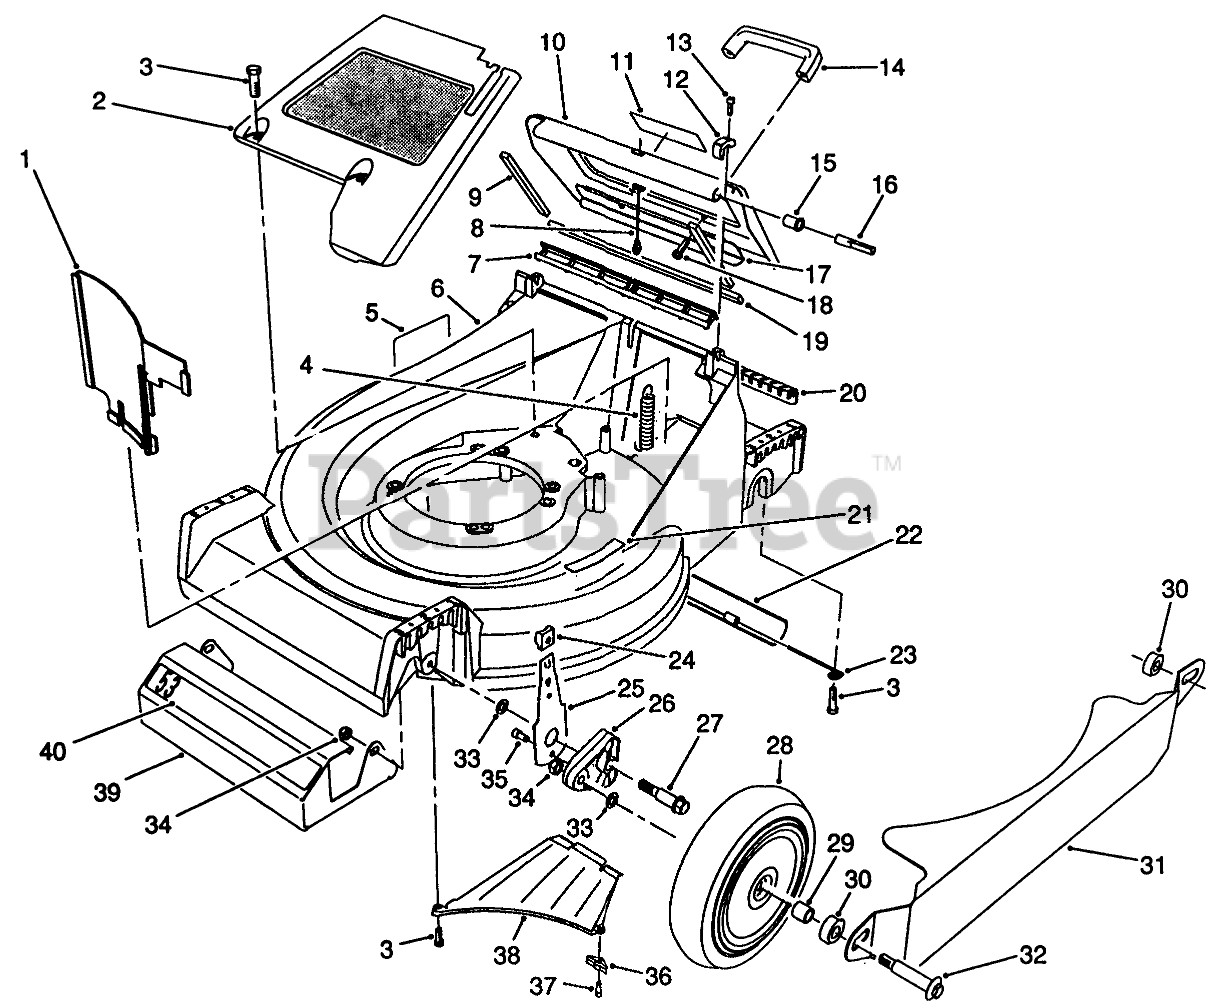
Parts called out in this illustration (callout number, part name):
1	PANEL-VERTICAL
2	PaneI-Screen
3	SCREW-HWHTF
4	EXTENSION-SPRING
5	Decal Danger
6	Housing-53cm (Incl. Ref. #5 & 21)
7	DOOR SEAL
8	DOOR CABLE
9	DOOR SIDE SEAL
10	Door-Discharge (Incl. Ref. #9, 11, 17 & 19)
11	Decal-Warning
12	HINGE CLAMP
13	SCREW-HSH
14	HANDLE-DOOR
15	DOOR BUSHING
16	HINGE PIN
17	DOOR - BRACE
18	SCREW-HWH
19	DOOR END SEAL
20	ACCESS COVER
21	DECAL - STEP PAD INT'L
22	TRAILING SHIELD
23	LH SHIELD HANGER
24	KNOB-ARM
25	FRONT SPRING ARM ASM
26	ARM-PIVOT, FRONT
27	BOLT-SHOULDER
28	Wheel & Tire Assembly (Incl. Ref. #29)
29	BUSHING
30	Spacer
31	Shield-Side (L.H.)
32	WHEEL BOLT
33	WASHER
34	Nut
35	SCREW-HSH, THREAD FORMING
36	Bracket-Discharge
37	SCREW-HWHTF
38	Ramp Discharge
39	FRONT SHIELD
40	DECAL - 53 CM
